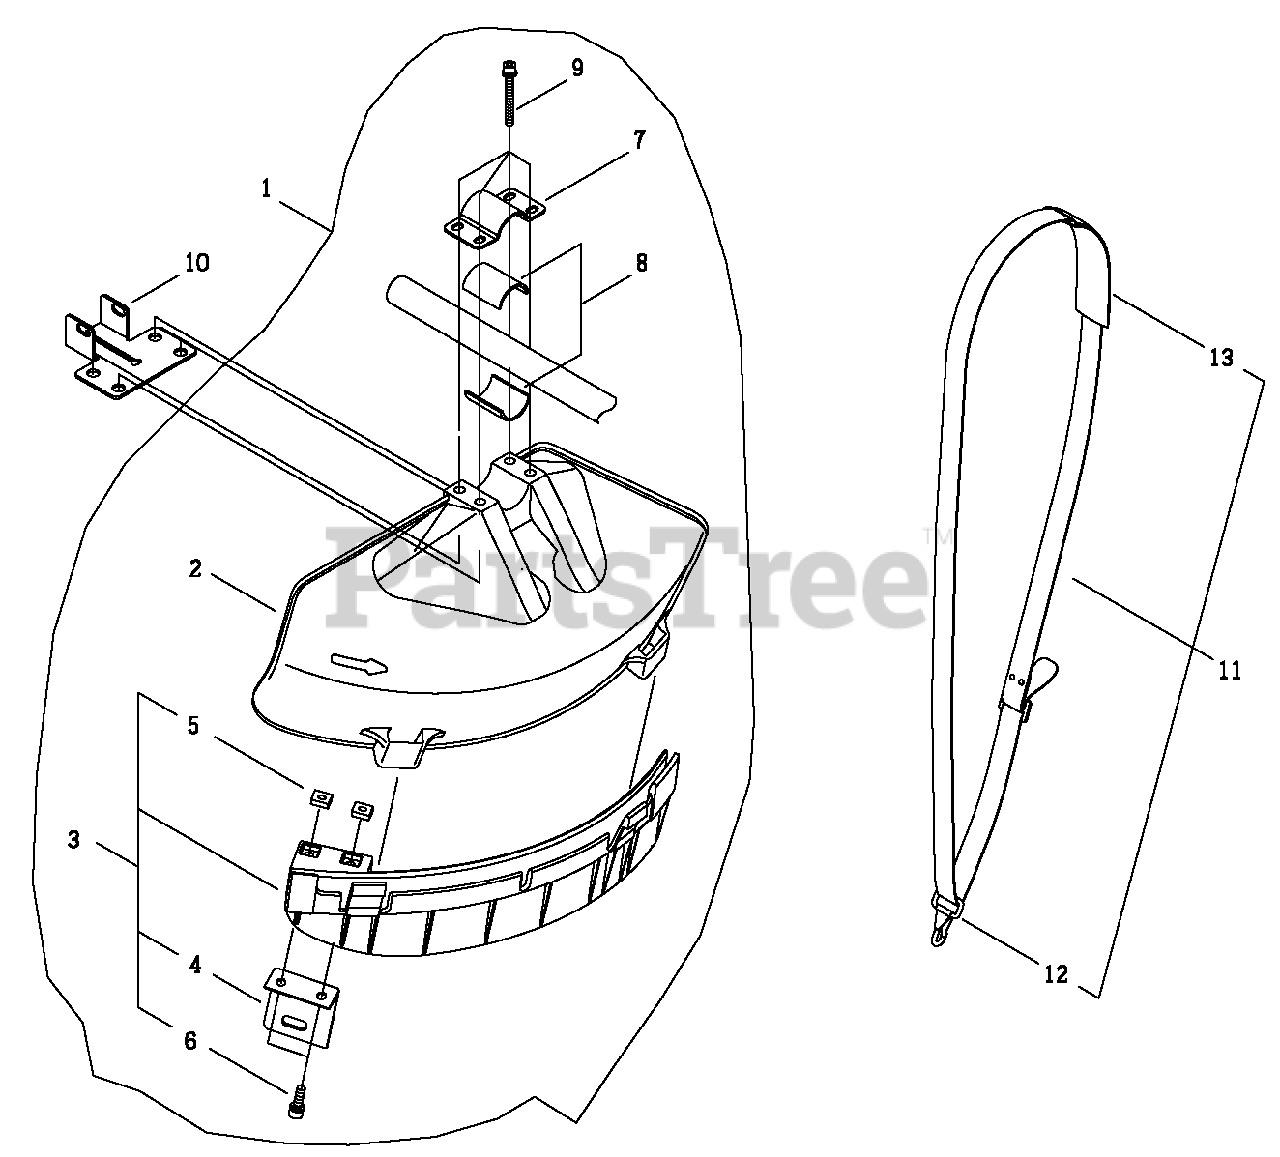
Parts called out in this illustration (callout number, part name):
1	DEBRIS SHIELD KIT
2	SHIELD, DEBRIS PLASTIC
3	DEBRIS SHIELD EXTENSION ASSY
4	CUTTER
5	NUT M5
6	BOLT M5×16
7	CLAMP, UPPER
8	SPACER 24
9	BOLT M5×45
10	PLATE, SHIELD MOUNTING
11	HARNESS ASSY
12	HOOK, SNAP
13	PAD, SHOULDER
